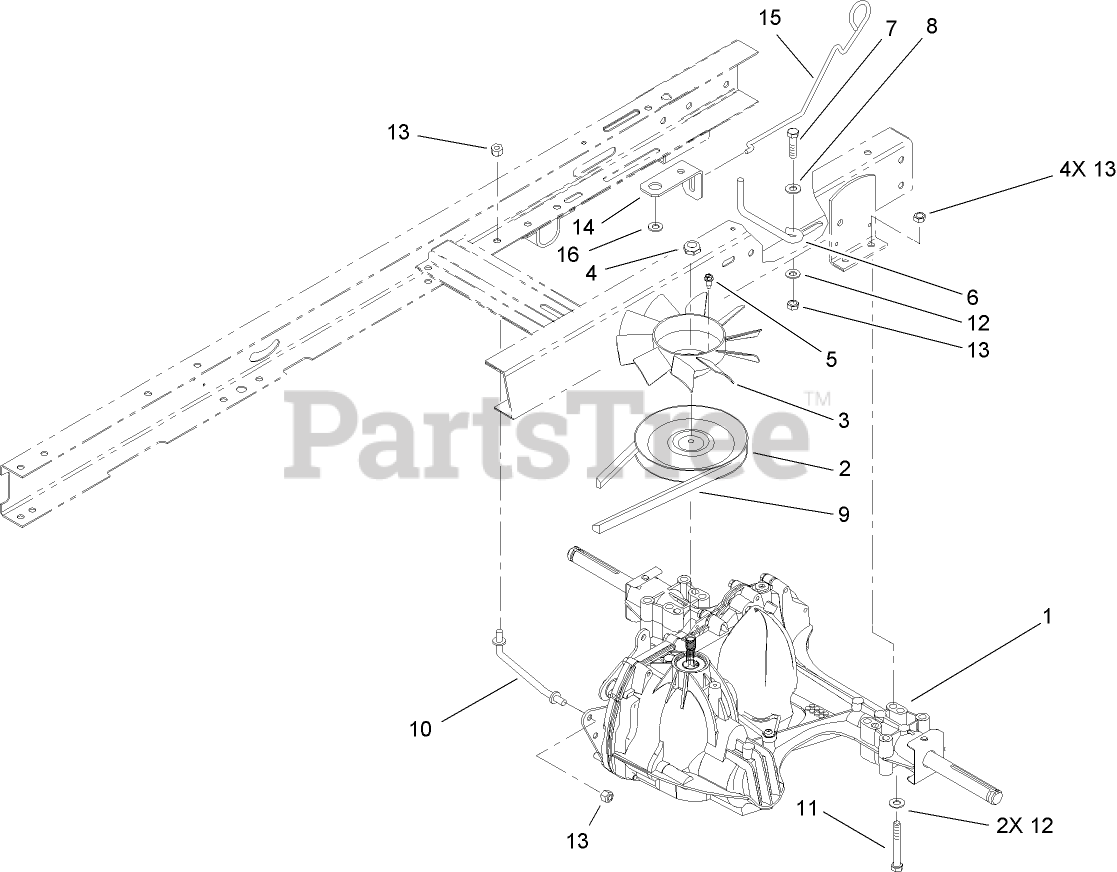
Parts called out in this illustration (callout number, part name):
1	TRANSAXLE ASM
2	PULLEY
4	NUT-LOCK, NI
5	SCREW-HWH
6	GUIDE-BELT
7	SCREW-HH
8	WASHER-PIVOT
9	V-BELT
10	STRAP-TORQUE
11	SCREW-HH
12	WASHER-PLAIN
13	NUT-LOCK, NI
14	BRACKET-BYPASS
15	ROD-BYPASS
16	WASHER-FLAT
